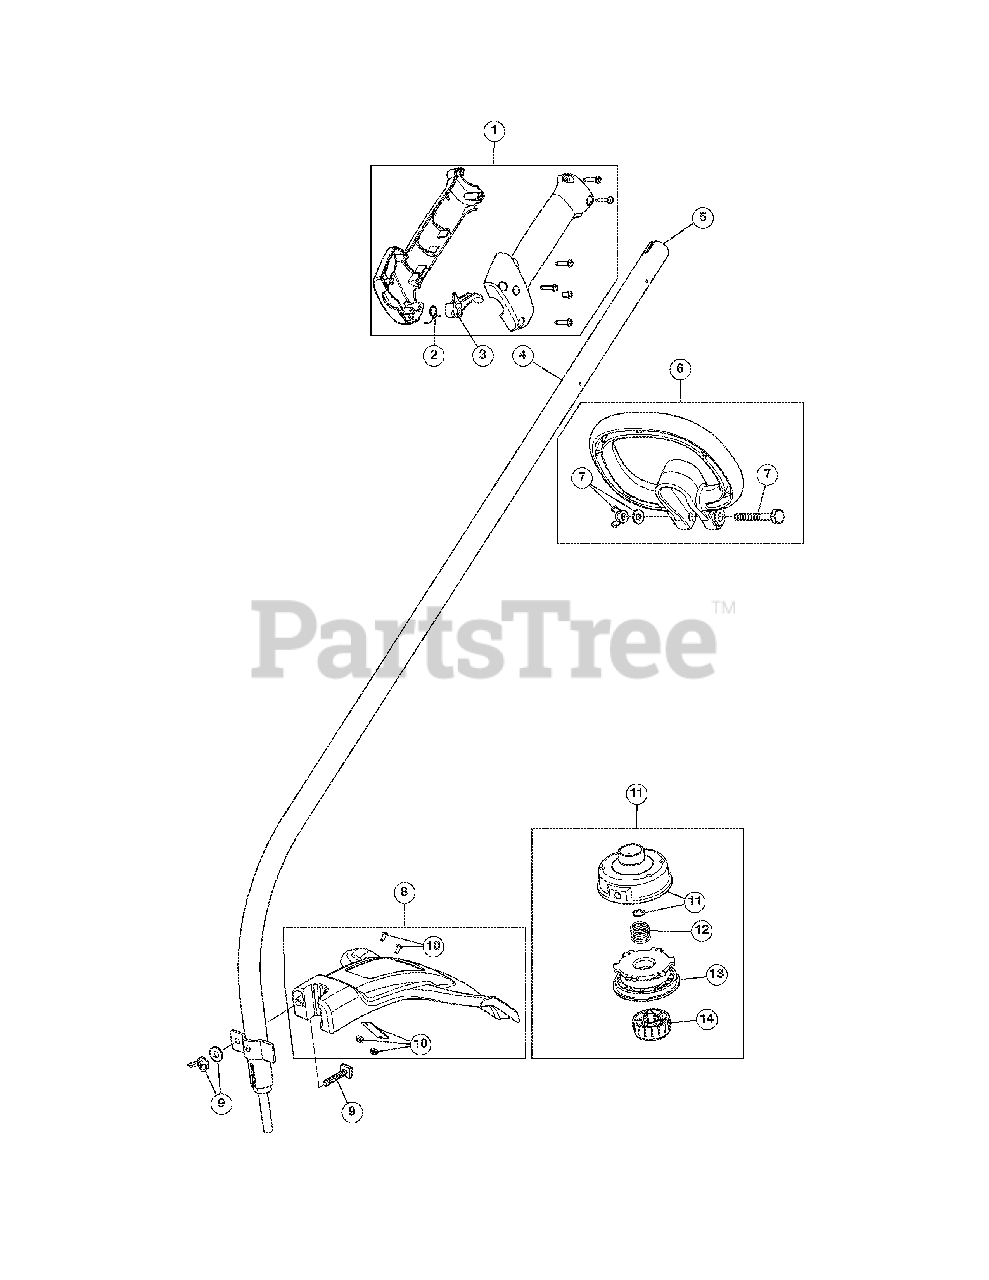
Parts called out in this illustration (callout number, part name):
1	Throttle Housing Assembly (Incl. 2 & 3)
2	Throttle Trigger Spring
3	Throttle Trigger
4	Drive Shaft Housing Assembly (Incl. 5)
5	Flexible Drive Shaft
6	D-Handle Assembly (Incl. 7)
7	D-Handle Hardware
8	Shield Assembly (Incl. 9 & 10)
9	Shield Mounting Hardware
10	Blade Assembly
11	Outer Spool Assembly (with Retainer)
13	Inner Reel
14	Bump Head Knob Assembly
